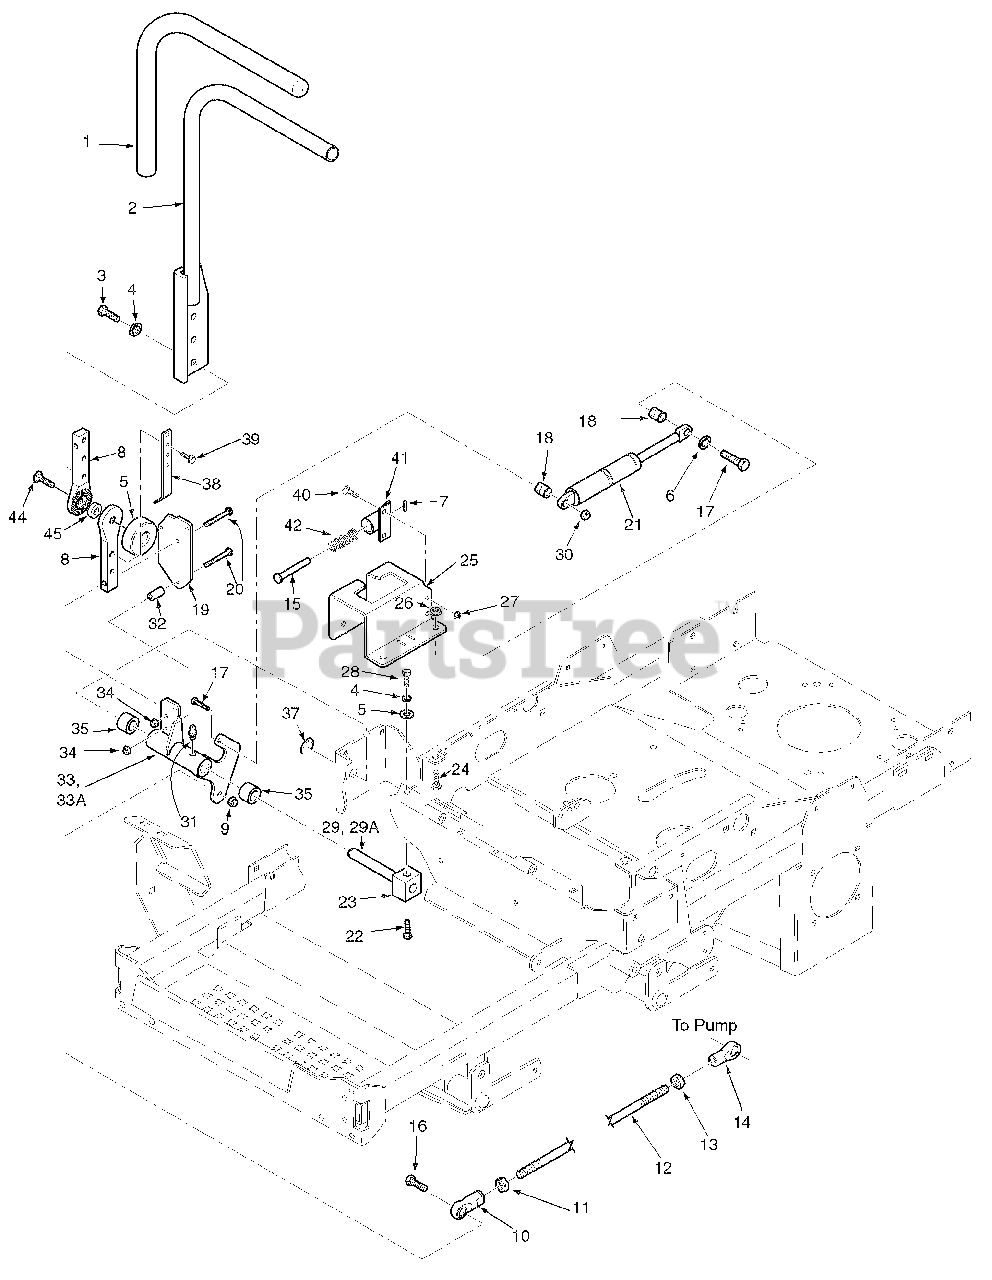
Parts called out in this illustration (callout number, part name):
1	Grip, Control Lever
2	Handle Bar, L.H.
3	Bolt, Hex Head 5/16-18 x 1"
4	Lock Washer, 5/16"
6	Flatwasher, 5/16-.375 x .875 x .083
7	Roll Pin, Spring 5/32 x 3/4"
8	Pivot, Control Lever
9	Nut, Elastic Stop 3/8-16
10	Rod End, 3/8-24 RH Female
11	Nut, 3/8-24 RH Thread
12	Rod, Pump Control Linkage
13	Nut, 3/8-24 UNF-2B LH Thread
14	Rod End, 3/8-24 LH Thread
15	Pin Retainer
16	Bolt, Hex Head 3/8-16 x 1-1/2"
17	Bolt, Hex Head 5/16-18 x 1-3/4"
18	Spacer, Pump Dampener
19	Plate, Control Lever
20	Bolt, Hex Head 5/16-18 x 2"
21	Gas Damper
22	Bolt, Hex Head 3/8-16 x 1"
23	Block, Clamping
24	Bolt, Carriage, 5/16-18 x 3/4"
25	Control Plate - LH
26	Nut, Serr., Flange, 5/16-18
27	Nut, Elastic Stop 1/4-20
28	Bolt, Hex Head 3/8-16 x 3/4"
29	Shaft, Steering Control
30	Nut, Elastic Stop 5/16-18
31	Grease Fitting, 1/4-28 Self Tap
32	Spacer, Control
33	Control Lever Assy RH
34	Nut, Elastic Stop 5/16-18
35	Bushing
36	Flatwasher, 1-1/4 x 49/64 x 16 Ga.
37	Retaining Ring, 3/4" Ext.
38	Bracket, Switch Actuator
39	Bolt, Hex Serr. Flange 5/16-18 x 3/4"
40	Bolt, Carr. 1/4-20 x 3/4"
41	Bracket, Control Return
42	Spring
43	Pin Retainer
44	Bolt, Carriage 5/16-18 x 1-1/2"
45	Rubber Spacer
